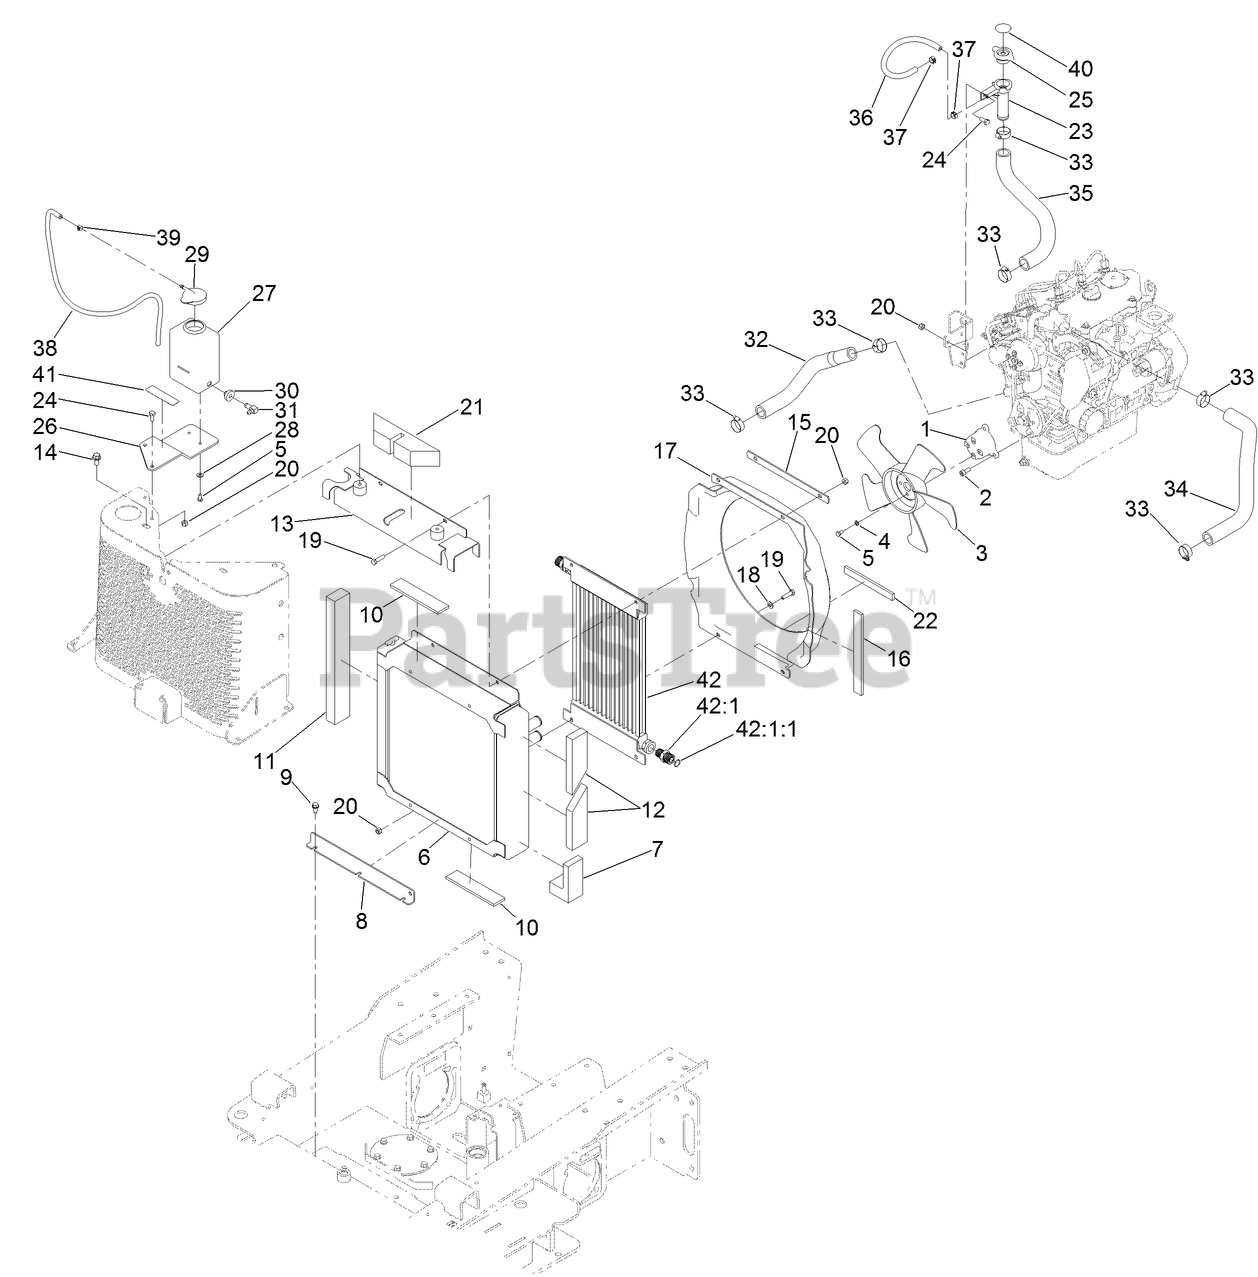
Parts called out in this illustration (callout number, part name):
1	SPACER-MACHINED
2	SCREW-CAP, HSH
4	WASHER-LOCK
5	SCREW-HH
6	RADIATOR
7	SEAL-FOAM
8	MOUNT-RADIATOR
9	SCREW-THD ROLL, HWH
10	PAD-RUBBER
11	SEAL-FOAM
12	SEAL-FOAM
13	BRACKET-RADIATOR
14	SCREW-HHF
15	PLATE-BACKING
16	FOAM-SEAL
17	SHROUD-FAN
18	WASHER-PLAIN
19	SCREW-HH
20	NUT-LOCK, NI
21	SEAL-FOAM
22	PAD-RUBBER
23	TUBE-FILLER RADIATOR
24	SCREW-HH
25	CAP-RADIATOR
26	BRACKET-TANK, OVERFLOW
27	TANK-OVERFLOW
28	WASHER-FLAT
29	CAP-TANK, OVERFLOW
30	BUSHING
31	FITTING-ELBOW, 90 DEG
32	HOSE-RADIATOR
33	CLAMP-HOSE
34	HOSE-RADIATOR, LOWER
35	HOSE-RADIATOR
36	HOSE-LP
37	CLAMP-HOSE
38	HOSE-LP
39	CLAMP-HOSE
40	DECAL-CAP, RADIATOR
41	DECAL-RADIATOR FILL
42	COOLER-OIL, HYD
42:1	FITTING-STRAIGHT
42:1:1	O-RING
